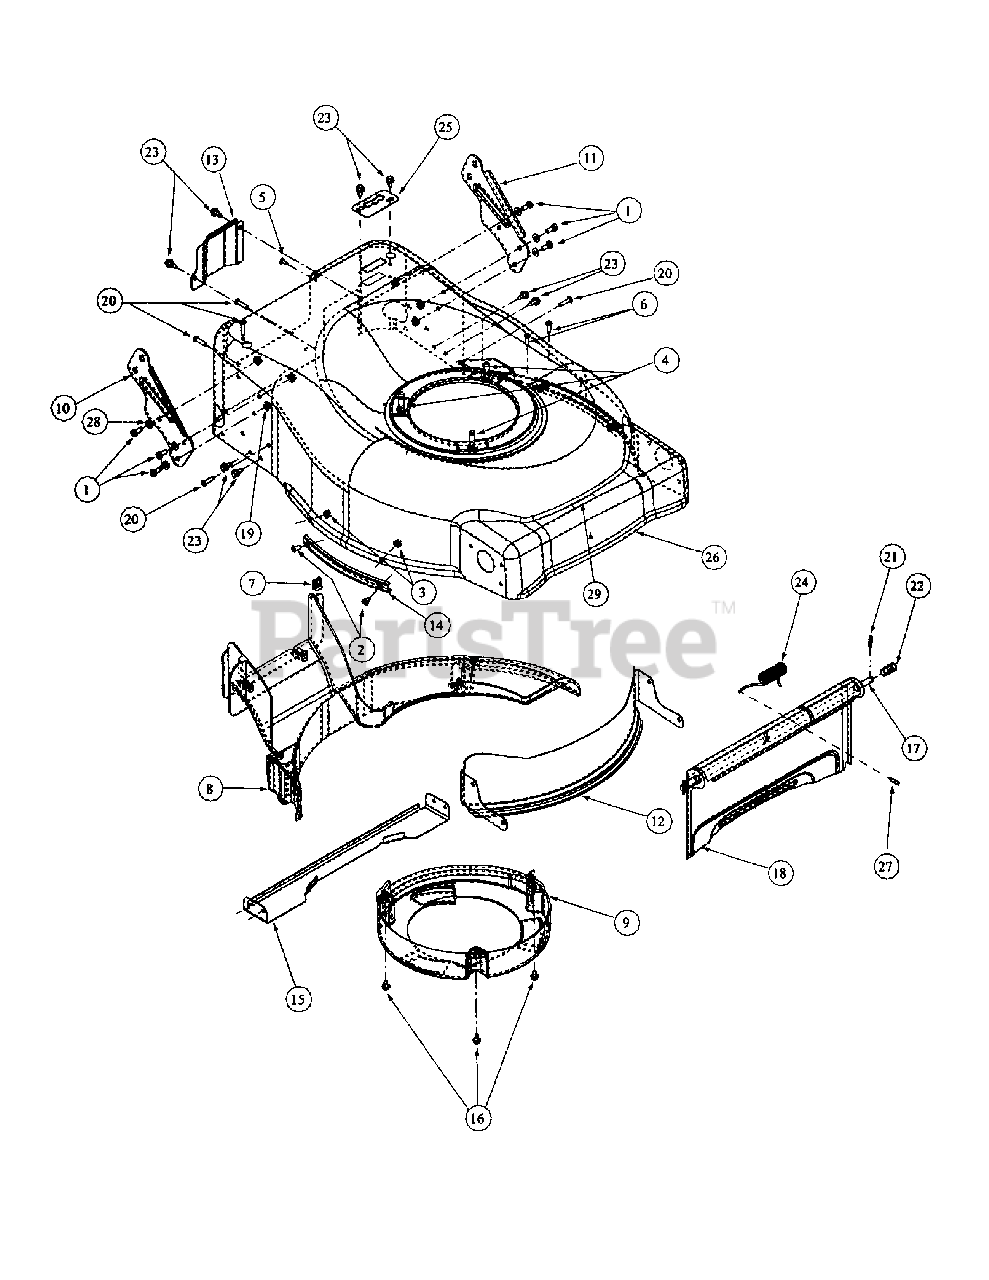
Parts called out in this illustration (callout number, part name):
1	HHCS, 1/4-20, .620, GR5, Standard
2	Screw Button HD, 1/4-20 x .5
3	Hex, Lock Nut, 1/4-20
4	Screw, TTSems, 3/8-16, 1.250, HXLWS
5	Screw, B, 10-16, 0.500, TRUSTRX1
6	Screw, HL, 12-16 0.750, TRUSTRX1
7	U-Nut, 10-16
8	Baffle, RR, 21" Commercial
9	Cover, 21" Commercial
10	Bracket, Handle, RH Commercial
11	Bracket, Handle, LH Commercial
12	Baffle Front Commercial 10 81 R
13	Cover Plate, Transmission
14	Guard, Deck Side Flange
15	Bracket, Support Baffle
16	Screw, TT, 1/4-20, 0.375, Hex Indicator Washer
17	Rod, Pivot, Chute Door, 375 D1
18	Door, Grassbag, 21" RB
19	Nut, 1/4-20, Hex Flange, Lock Group F
20	Screw, HL, 12-16, 1.000, TRUSTRXI
21	Cotter Pin, INT .072 x 1.12 LG
22	Spacer, .375 x .50 x 1.02 LG
23	Screw, AB, 1/4-14, 0.625, Hex Indicator Washer
24	Spacer, Torsion, LH 0.120 x 15C
25	Shifter, Selector, Bracket
26	21" Commercial, Round Deck
27	Vinyl, Cap Spring
28	Flat Washer, 1/4 x .630 x .0515
29	Label, 21" Commercial
